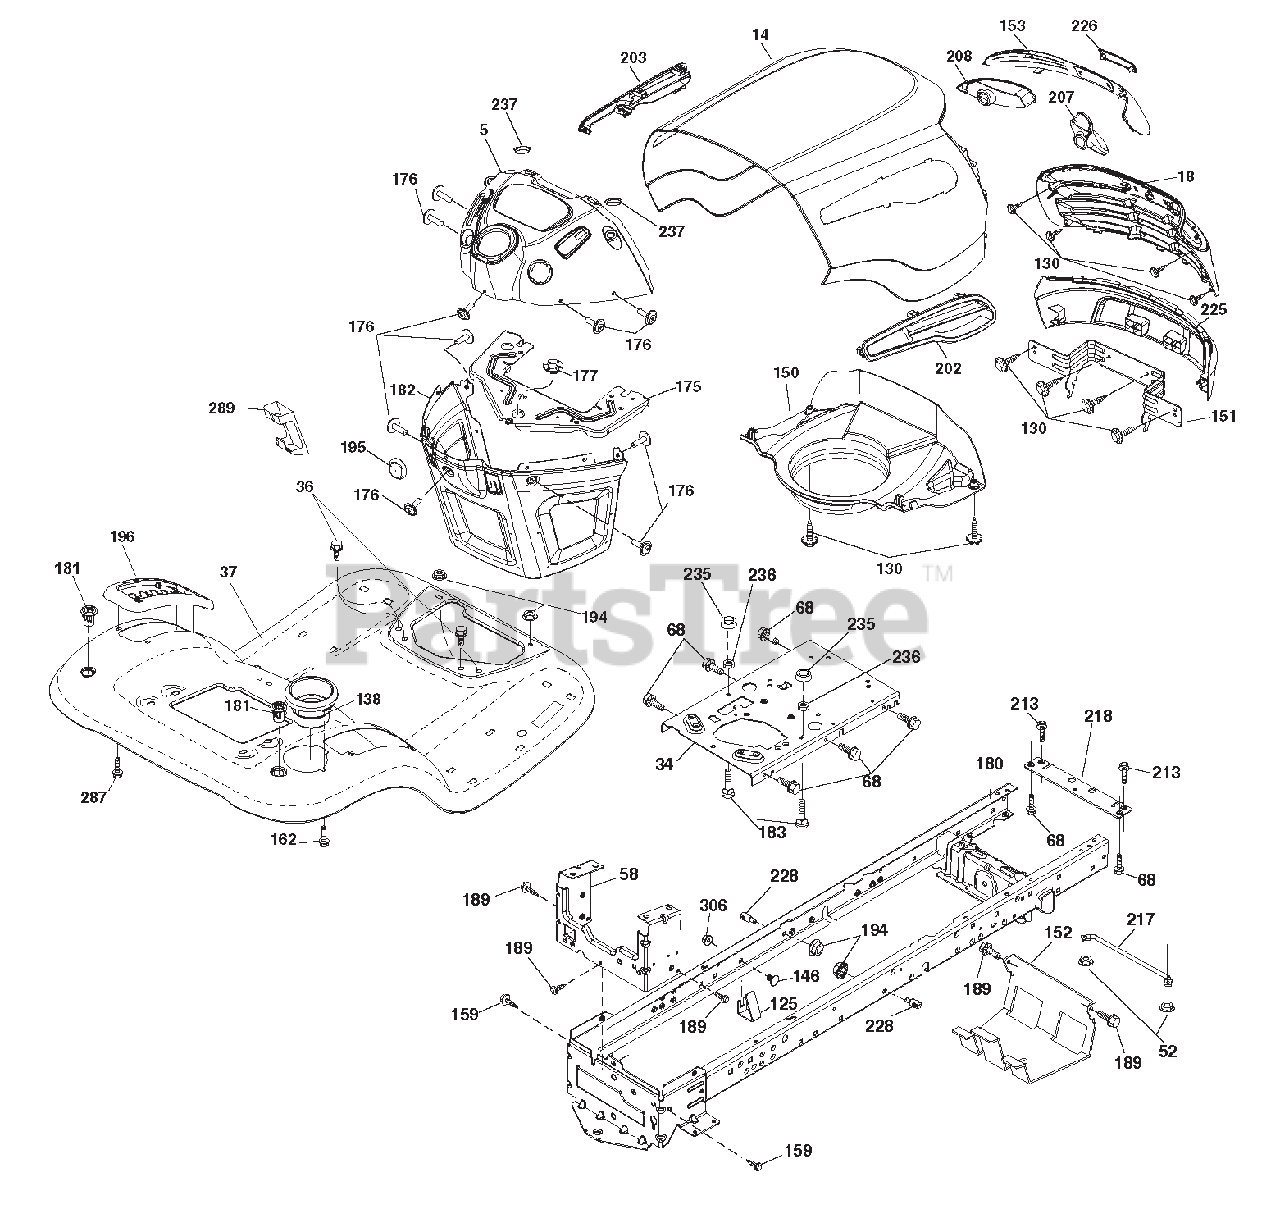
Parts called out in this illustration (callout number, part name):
5	DASH.P/L.TEX.CABLE
18	GRILLE.ELITE.ARIENS.BLACK
34	PLATE.ENGINE.WELDED.CHASSIS
36	SCREW.5/16-18X3/4.SMGML.TAP/R
37	FENDER TLT W/CPH W/FW 422
52	Nut, Hex, Crownlock 5/16-18
58	DRAWBAR.UPPER.2PC.SML.FENDER
68	SCREW.THDROL.5/16-18 X 1/2TYTT
125	CLIP.FUEL.LINE
138	CUPHOLDER TL TEX 428
150	AIR DUCT
151	BRACKET.PIVOT
152	SHIELD.BROWNING.W/TEX
153	LENS.BAR
159	SCREW.HEXWSH THDR3/8-16X3/4.BL
162	SCREW.HEX.WSH.HI-LO.1/4X1/2UNC
175	CROSSMEMBER.LT
176	SCREW.#10-24X5/8.RND.QUDRX.GIM
177	BUSHING.STEERING.YT/GT
180	CHASS.WLDMT.TL.12GA/2PC.18/22"
181	BUSHING MNT FEND CRGO BLK TEX
182	DASH.LOWER.LT.CCS
183	BOLT.FIN.HEX.5/16-18 UNC X1-1/
189	SCREW.5/16-18X3/4.SMGML.TAP/BL
194	Nut, Lock Hex Flange 5/16-18 u
195	PLUG HOLE DASH TOWER
196	CONSLE.ASM.DECK.LFT.BL/RBT.TLT
202	VENT RH
203	VENT.SIDE.LH
207	BEZEL.LH
208	BEZEL.RH
213	BOLT.HEX.HD.1/4-20UNC X 3/4
217	ROD.PIVOT.HOOD
218	X-PIECE.HOOD.STOP.NON/STEALTH
226	ARIENS.LOGO.PLATE
228	STUD.FASTNER.W/'D'ANTI-ROTATIO
235	SPACER.FENDER
236	NUT.CENTER LOCK.5/16-18 UNC
237	PLUG.MOUNT.CARGO
287	SCREW.HEX.WASHEAD.1/4-20 X 3/8
289	PLUG.CRUISE.CONTROL
306	Nut, Hex, Flangelock 3/8-16
